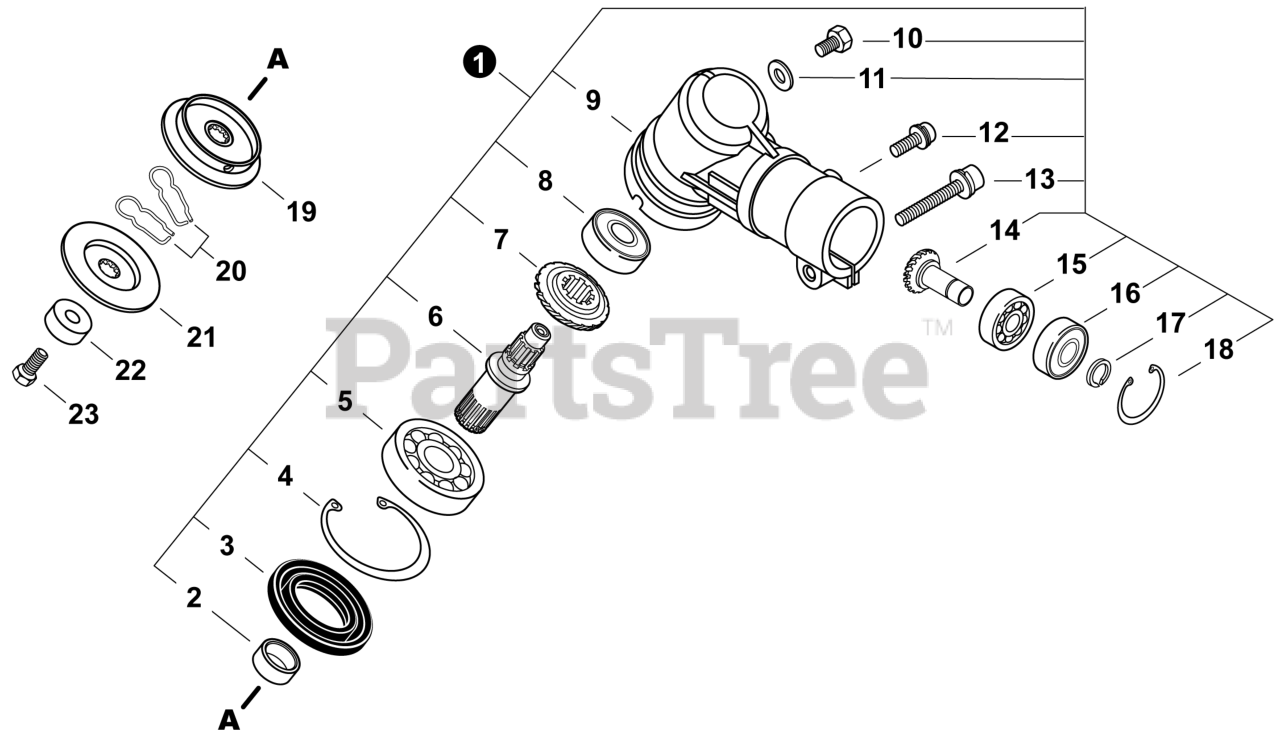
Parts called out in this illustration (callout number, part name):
1	GEAR CASE ASSY
3	SEAL, OIL
4	RING, SNAP 35
5	BEARING, BALL 6202
6	SHAFT, GEAR
7	GEAR, BEVEL
8	BEARING, BALL 6000DDU
9	HOUSING, GEAR CASE
10	BOLT M6x10
12	BOLT M6x14
13	BOLT M6x40
14	PINION ASSY, BEVEL
15	BEARING, BALL 6001
16	BEARING, BALL 6001ZZ
17	RING, SNAP 12
18	RING, SNAP 28
19	PLATE, ADAPTOR - UPPER
20	PIN, SLIDE
21	PLATE, ADAPTOR - LOWER
22	GUARD, BOLT
23	BOLT 10
24	NUT, HEX M6
25	WASHER 6.5x13x1
26	CLAMP, LOWER
